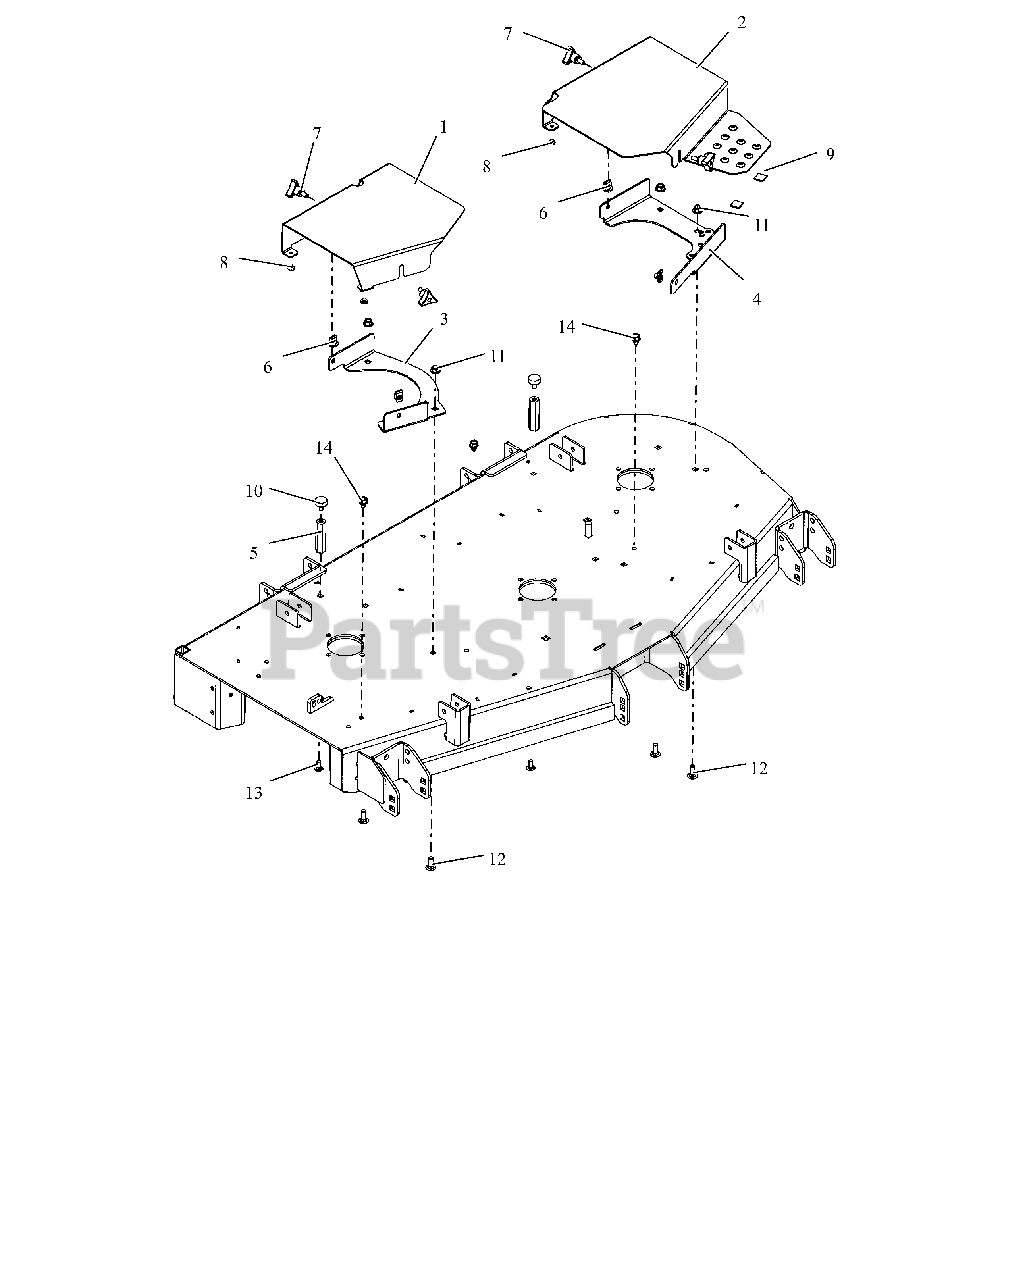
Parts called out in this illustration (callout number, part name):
1	GUARD, RH DECK - RED
2	GUARD, LH BELT - RED
3	BRKT, RH BELT GUARD MTG - RED
4	BRKT, LH BELT GUARD MTG - RED
5	NUT, COUPLING .31-18 X 3.00
6	NUT-CLIP RETAINER 5/16-18X.56
7	KNOB,WING STUD 5/16-18 X .75
8	BUMPER GROMMET
10	BUMPER, RUBBER
11	NUT,NYL-FLG .38-16 GF ZCC
12	BLT, RHSN .38-16X1.00 G5 ZCC
13	BTL,RHSN .313-18 X 0.75 G5 ZCC LT
14	SCR,TAP .375-16X.50 HWH TR ZCC
